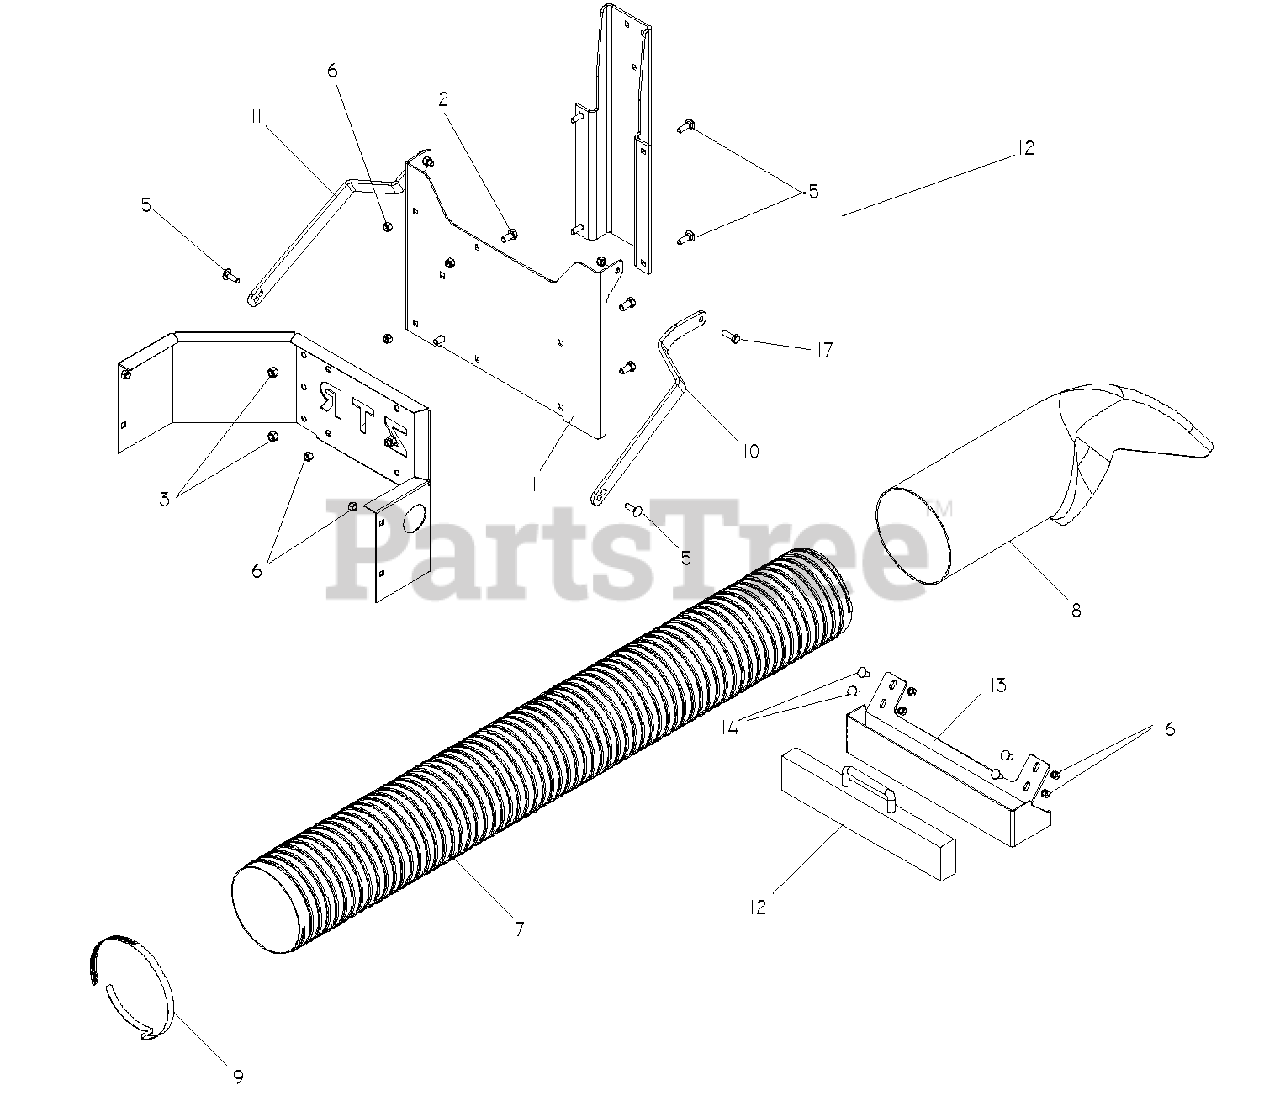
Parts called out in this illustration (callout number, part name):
1	SUPPORT - BAGGER
2	SCREW 3/8C X 3/4 HEX CAP
3	NUT 3/8-16 NYLOC
4	BRACKET, HANGER
5	RHSNB 5/16C X 1
6	NUT 5/16 NYLOC
7	FLEX HOSE 6 X 50
8	UPPER CHUTE - MODIFIED
9	HOSE CLAMP
10	SUPPORT STRAP - L.H.
11	SUPPORT STRAP - R.H.
12	CAST WEIGHT
13	BRACKET, WEIGHT
14	BOLT 5/16C X 3/4" CARRIAGE
15	HCS 5/16C X 1
